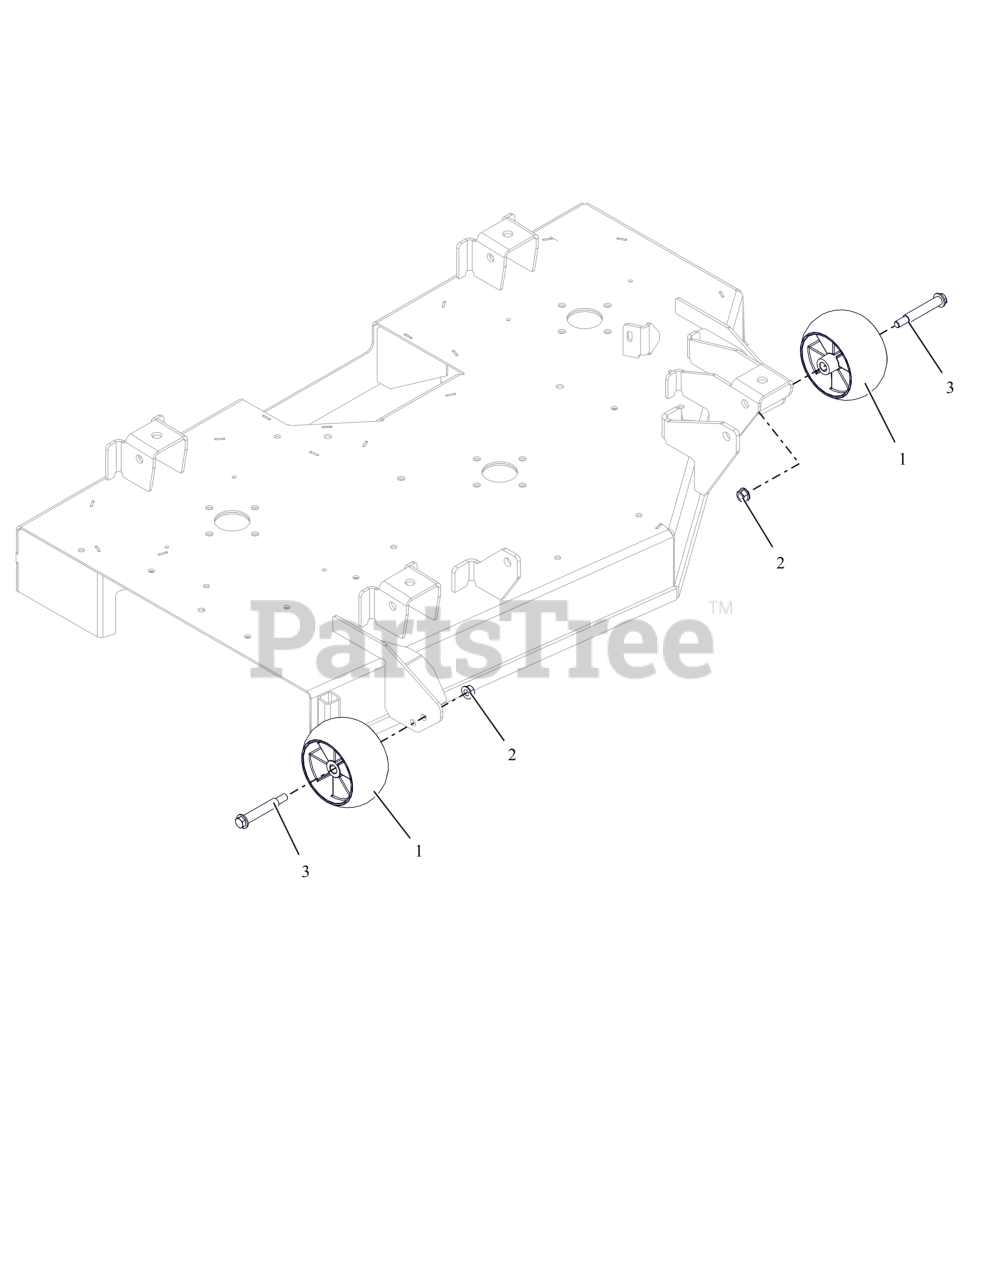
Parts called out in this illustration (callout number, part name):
1	ANTI-SCALP WHEEL - 5X OS
2	NUT-LK-CTR-FLG .375-16 GF ZCC
3	BLT-SHLDR .38-16X2.50 HWH G5
